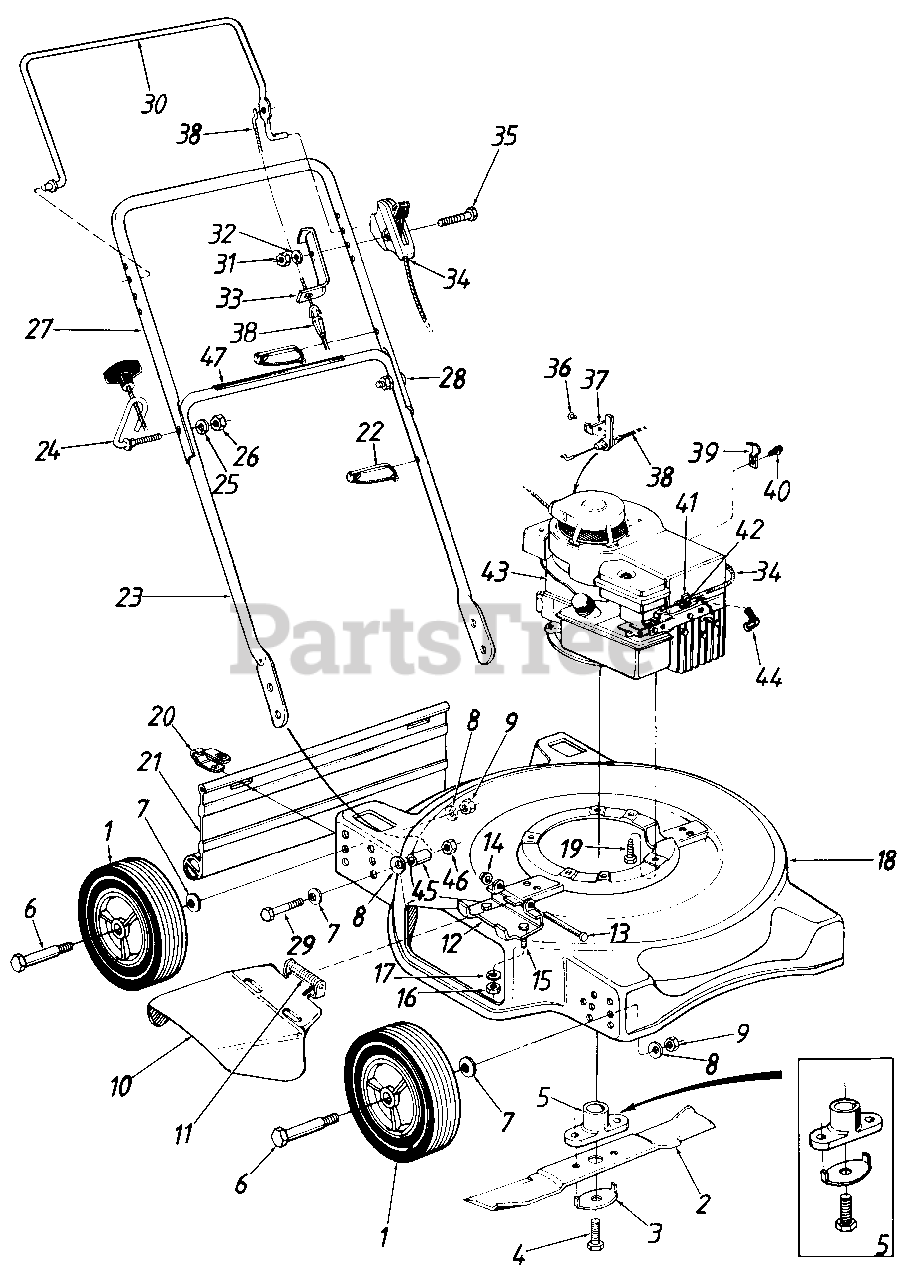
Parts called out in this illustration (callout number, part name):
1	Wheel Ass'y. Complete
2	20" Blade
3	Blade Bell-Wash. .45" I.D. x 2.38"
4	Hex Bolt 3/8-24 x 1.5" Lg.
5	Blade Adapter Kit
6	Shld. Bolt .498" Dia. x 1.64" Lg.
7	Bell-Wash. .380" I.D. x .88" 0. D.
8	Bell-Wash. .391" I.D. x 1.13" 0. D.
9	Hex Nut 3/8-16 Thd.
10	Chute Deflector Ass'y.
11	Torsion Spring
12	Adapter Plate
13	Pivot Pin
14	Speed Nut 1/4" Rod
15	Hex Bolt 1/4-20 X .5" Lg.
16	Hex Nut 1/4-20 Thd.
17	L-Wash. 1/4" I.D.
18	20" Deck Ass'y.
19	Hex Wash. Hd. Scr. 3/8-16 x 1" Lg.
20	Hinge Clip
21	Rear Flap 16.75" Lg.
22	Cable Tie
23	Lower Handle
24	Rope Guide Bolt
25	L-Wash. 5/16" I.D.
26	Hex Nut 5/16-18 Thd.
27	Upper Handle
28	Curved Carriage Bolt 5/16-18 x 1.38" Lg.
29	Hex Bolt 3/8-24 x 1.5" Lg. Grade 5
30	Control Handle
31	Hex Nut 1/4-28 Thd.
32	Spr. Wash. .265" I.D. x .562" O.D.
33	Cable Mounting Bracket
34	Throttle Control Ass'y. Comp.
35	Hex Bolt 1/4-28 x 1.75" Lg.
36	Pop Rivet .156" Dia. x .316
37	Cable Bracket
38	Control Cable 36"
39	Casing Clamp
40	Hex B-Tap Scr. #10 x .38" Lg.
41	Casing Clamp
42	Hex Wash. Hd. AB-Tap Scr. #8 x .50" Lg.
43	Engine
44	Spark Plug Boot
45	Spacer .381" I.D. x .56" O.D. x.75" Lg.
46	Hex Lock Nut 3/8-24 Thd.
47	Instruction Label Handle
